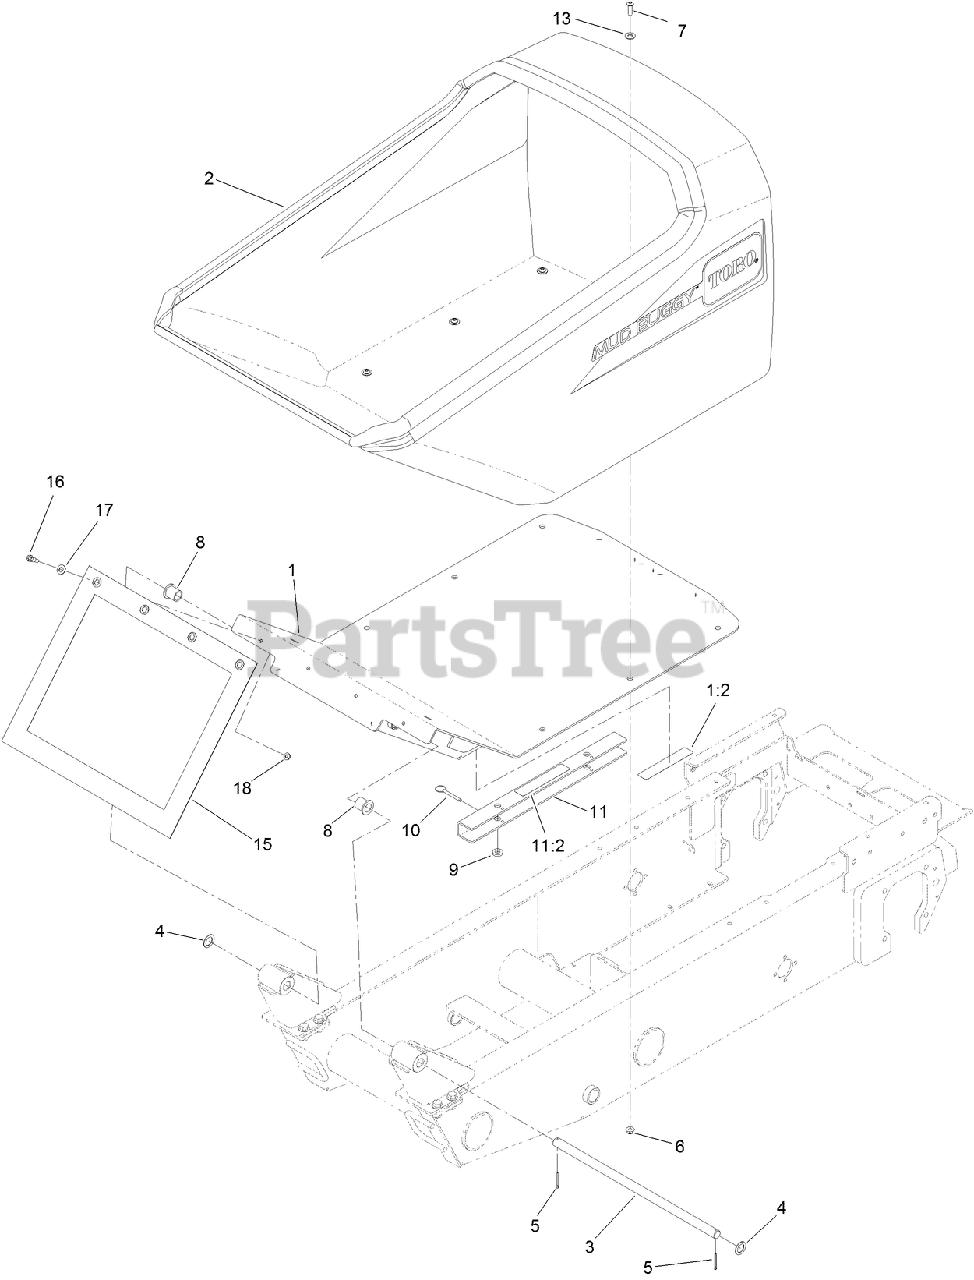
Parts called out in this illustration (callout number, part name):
1	HOPPER BASE ASM
1:2	DECAL-DANGER
2	HOPPER-MORTAR
3	SHAFT-PIVOT,TUB
4	SPACER
5	PIN-COTTER
6	NUT-HF, NI
7	SCREW-HSBH
8	BEARING-FLANGED
9	WASHER-NEOPRENE
10	PIN-COTTERLESS
11	ARM-LOCKING
11:2	DECAL-DANGER
13	WASHER-FLAT
15	SHIELD-SPLATTER
16	BOLT-SHOULDER
17	WASHER-FLAT
18	NUT-HF, NI
